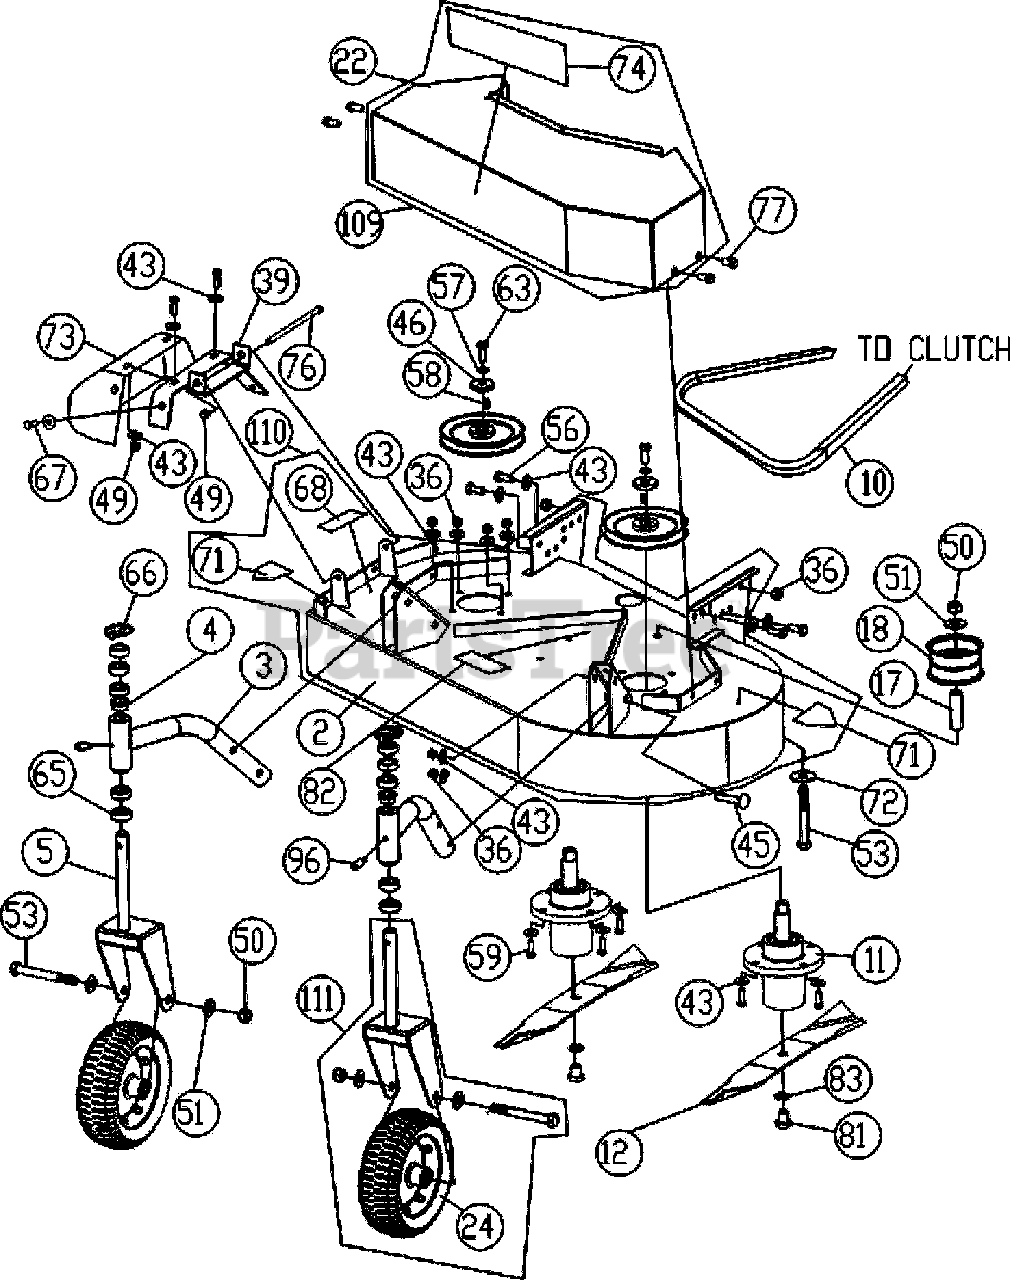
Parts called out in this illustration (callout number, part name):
2	Deck WA HP
3	Caster Arm WA HP
4	Bushing Flange 1" OD 3/4" ID
5	Caster Bracket WA HP
10	Belt 5l x 60
11	Spindle Assy w/Pulley
12	Blade 17.25"
17	Spacer Fixed Idler
18	Pulley Idler
22	Guard Belt HP
24	Wheel 8" od x 0.5" Bearing
36	Nut Lock 3/8" - 16
39	Bracket Mount Deflector
43	Washer 5/16 Flat ZP
45	Bolt Carriage 3/8-16 x 2"
46	Washer 1.5 OD x .453 ID x .25 THK
49	Nut Lock 5/16-18 HEX ZP
50	Nut Lock 1/2 - 13 HEX ZP
51	Washer 1/2" SAE ZP
53	Screwcap 1/2"-13 x 4 1/2" HCS ZP
56	Screwcap 3/8"-16 x 1" HCS ZP
57	Washer Lock 3/8" S/T Med
58	Key 3/16" sq x 5/8"
59	Screwcap 3/8" - 16 x 1/2" HCS ZP
63	Screwcap 3/8"-24 x 1" HCS Gr. 8
64	Washer Lock 1/4" External Tooth
65	Bushing Caster Yoke Spacer
66	Lynch Pin 3/16" x 1 9/16"
67	Screwcap 5/16-18 x 1" HEX ZP
68	Label Danger Flying Debris
71	Label Warning Rotating Blades
72	Impeller Washer Plated
73	Deflector Rubber
74	Label Badge Logo HP
76	Screwcap 5/16-18 x 6 1/2" HCS ZP
77	Screw self tap 5/16" x 3/4" HEX
81	Screwcap 5/8"-18 x 1" HCS GR. 8
82	Label Warning Guards
83	Washer Lock 5/8" S/T Med
96	Zerk Grease Fitting
109	Guard belt hp WA w/labels
110	Deck WA HP w/labels
111	Caster Assy HP kit
